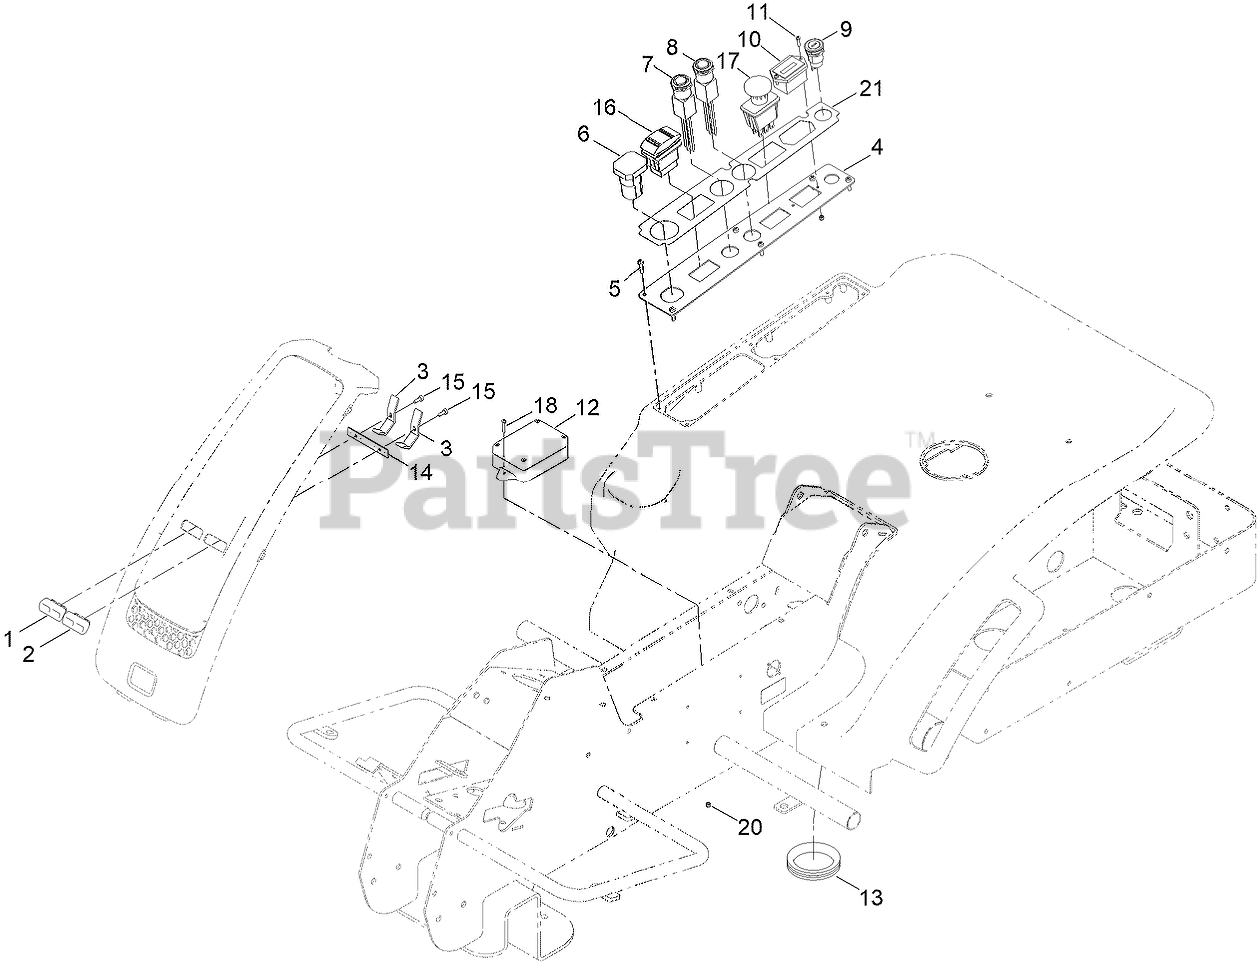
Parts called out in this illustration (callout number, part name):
1	CASING, LIGHT (RIGHT, FRONT)
2	CASING, LIGHT (LEFT, FRONT)
3	BRACKET, LED LIGHTS
4	PLATE, SWITCHES
6	USB SWITCH
7	RMO, BUTTON
8	CCT, BUTTON
9	SWITCH, IGNITION
10	INDICATOR, BATTERY LEVEL
12	CONTROL BOX, ASM
13	INSERT, RUBBER CABLE SMALL
14	PLATE, LIGHTS
16	DIRECTION SWITCH ASM
17	CUTTER BUTTON ASM
20	NUT-NYLOC
21	DECAL - CONTROL PANEL
